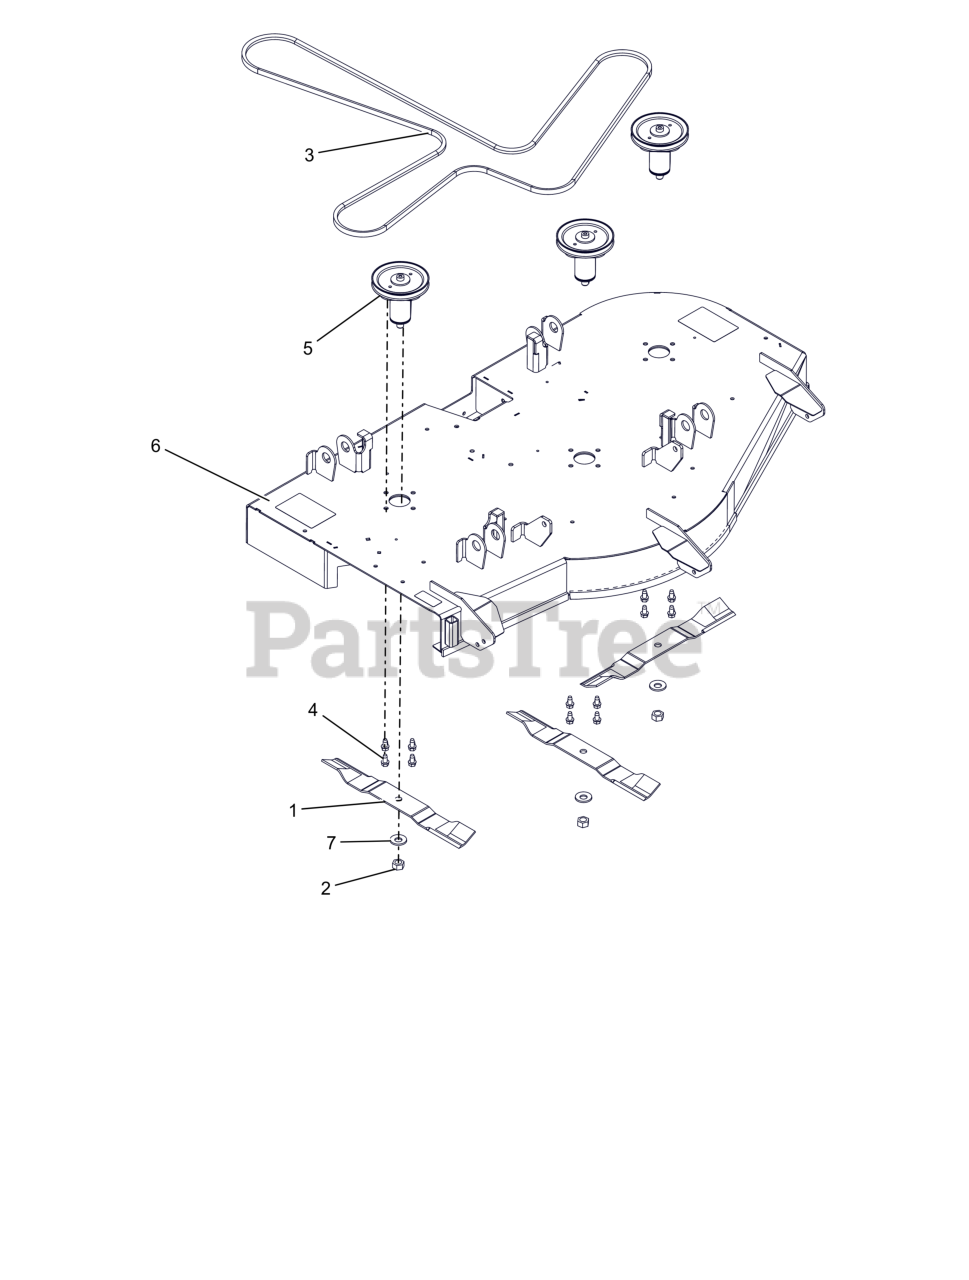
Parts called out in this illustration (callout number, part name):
1	BLADE, 18" - 30 DEG .5 OFFSET
2	NUT-HEX .62-18 YWZC
3	V-BELT, HA-WRAPPED
4	@SCR-TAP .38-16X.75 HWH TR YWZ
5	KIT, DECK SPINDLE ASM-52
6	KIT, 52" ARIENS DECK W/DECALS
7	WSHR-BLVL .669X1.535X.138
